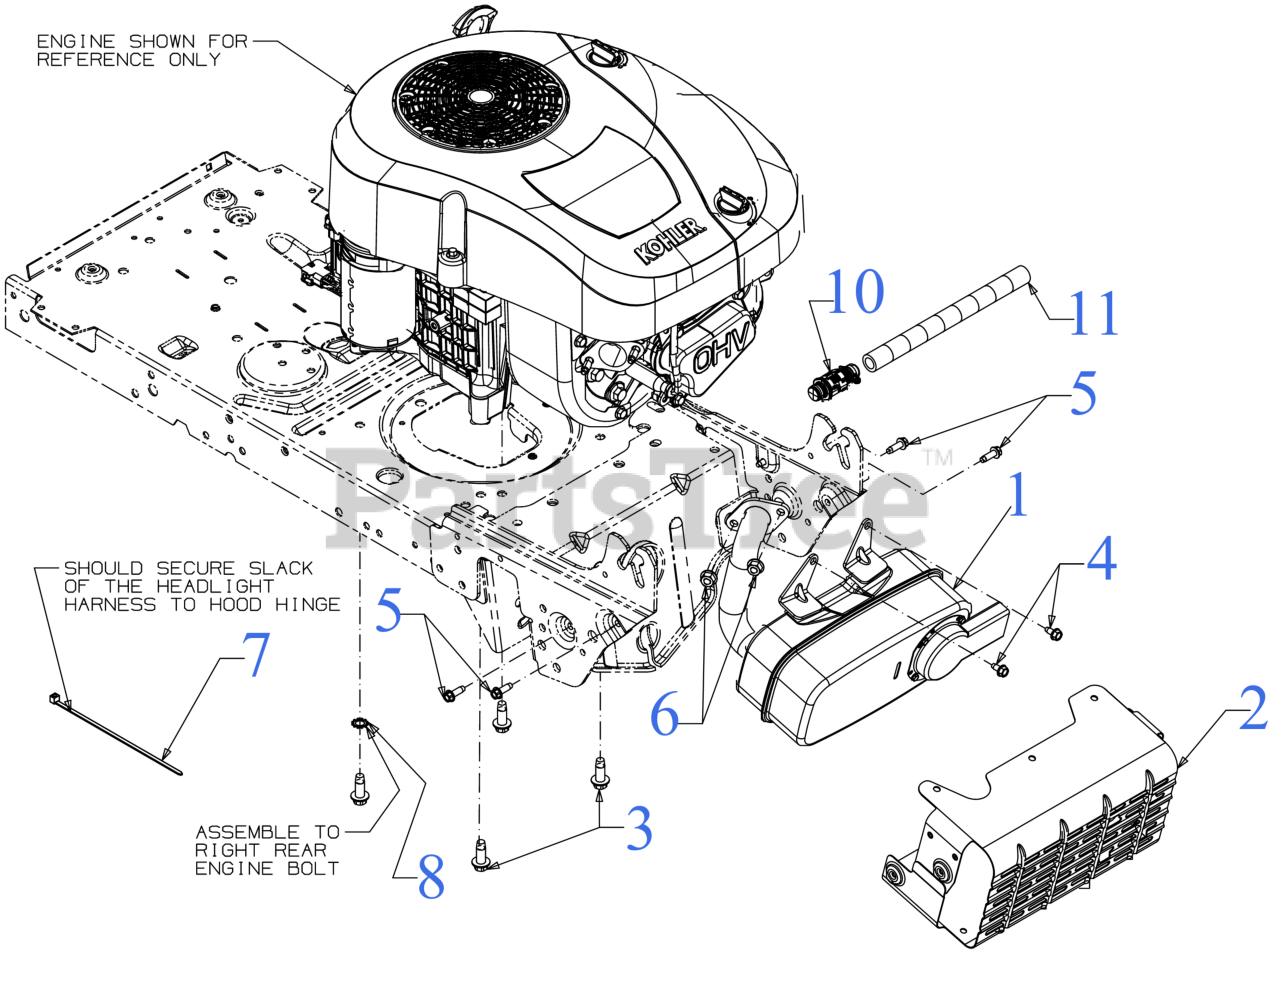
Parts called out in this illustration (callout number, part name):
1	EXHAUST DELECTOR (LONG)
2	MUFFLER SHIELD
3	SCREW 3/8-16 x 1
4	SCREW 1/4-20 X.500
5	SCREW 1/4-20 x .750
6	HEX FLANGE NUT M8X
7	7" CABLE TIE
8	LOCK WASHER 3/8
10	OIL DRAIN VALVE
11	DRAIN HOSE 14''
